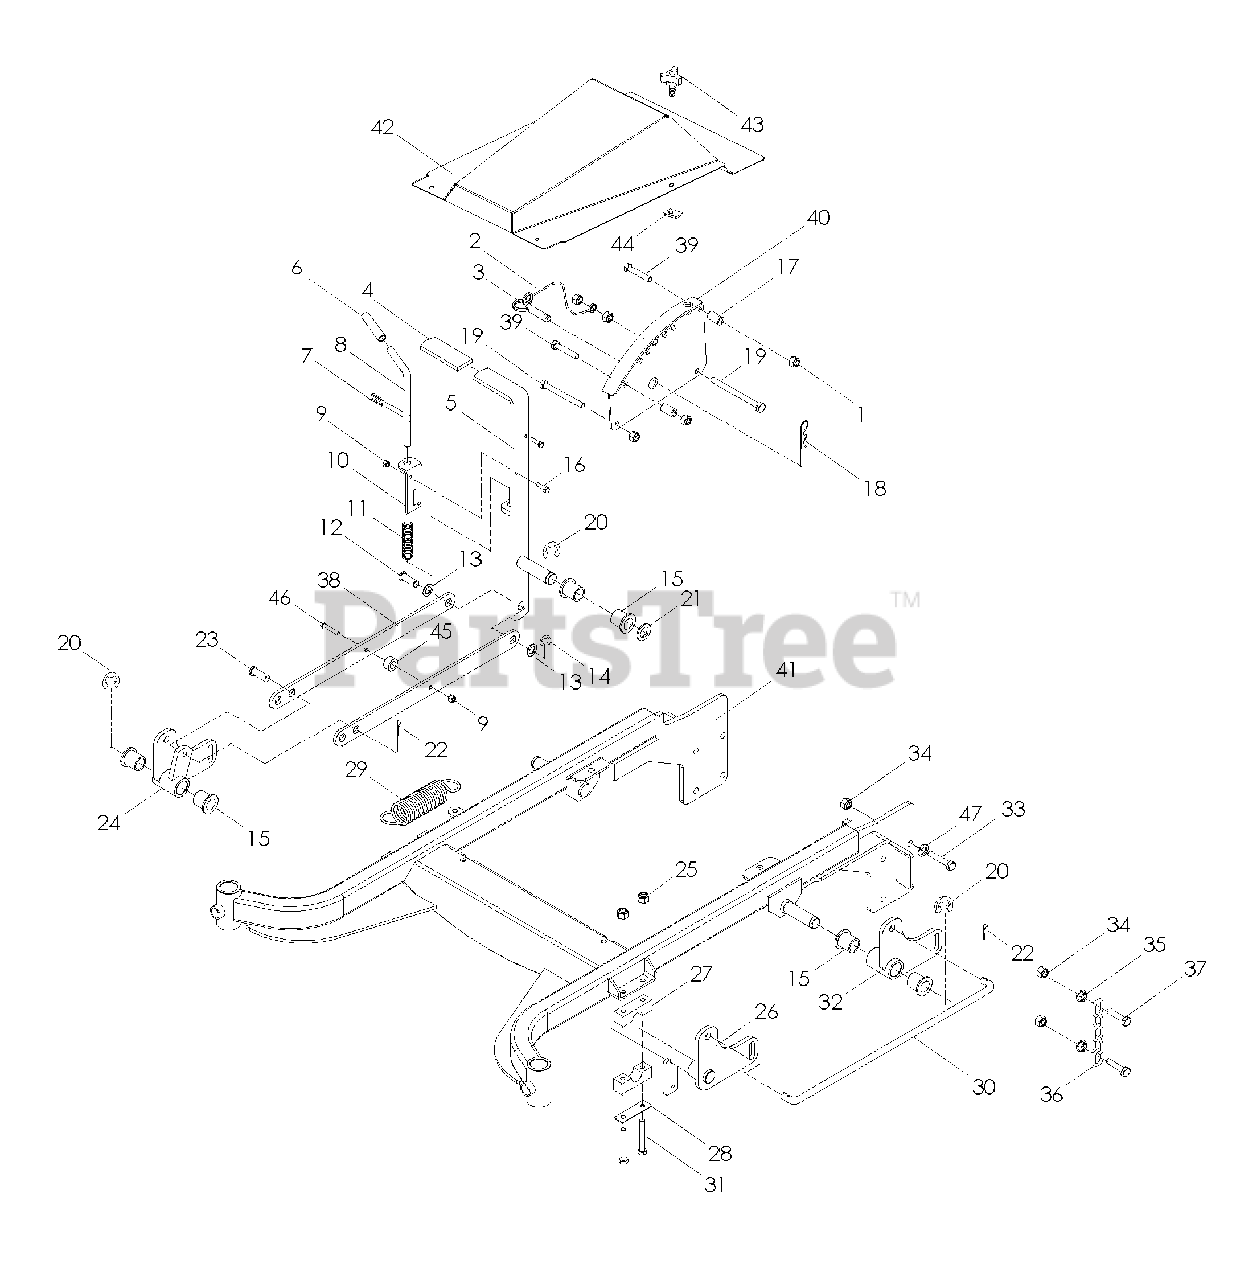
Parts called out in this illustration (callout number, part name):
1	NUT 3/8-16 HEX CNTRLK
4	GRIP, LIFT LEVER
5	LEVER, LIFT
7	PIN, GROOVED
8	PIN, LIFT LEVER
9	NUT 1/4-20 CNTRLK
10	MOUNT, PIN
12	CLEVIS PIN
13	BUSHING 5/8 MACHINERY
14	E-RING 5/8
15	BUSHING 7/8 FLANGED
16	HCS 1/4-20 x 3/4
18	HAIRPIN 21/2
19	HCS 3/8-16 x 4 1/2
20	E-RING 7/8
21	BUSHING, MACHINE
22	PIN, COTTER 5/32 x 1 1/4
23	PIN, CLEVIS 3/8 x 1 1/8
24	BELLCRANK, RIGHT
25	NUT 5/16-18 HEX CTRLK
26	LIFT ARM, FRONT
27	BLOCK, PILLOW
28	PLATE, REINFORCEMENT
30	LINK, DECK LIFT
31	HCS 5/16-18 x 2 1/2
32	BELLCRANK, LEFT
33	HCS 7/16-14 x 1
34	NUT 7/16-14 CNTRLK
35	NUT 7/16-14 WHIZ
36	CHAIN, LIFT
37	HCS 7/16-14 x 1 1/2
38	LINKAGE, FLAT
39	HCS 3/8-16 x 2
40	PLATE, HEIGHT ADJUST
43	KNOB
46	HCS 1/4-20 x 1 1/4
47	WASHER 3/8 FLAT
